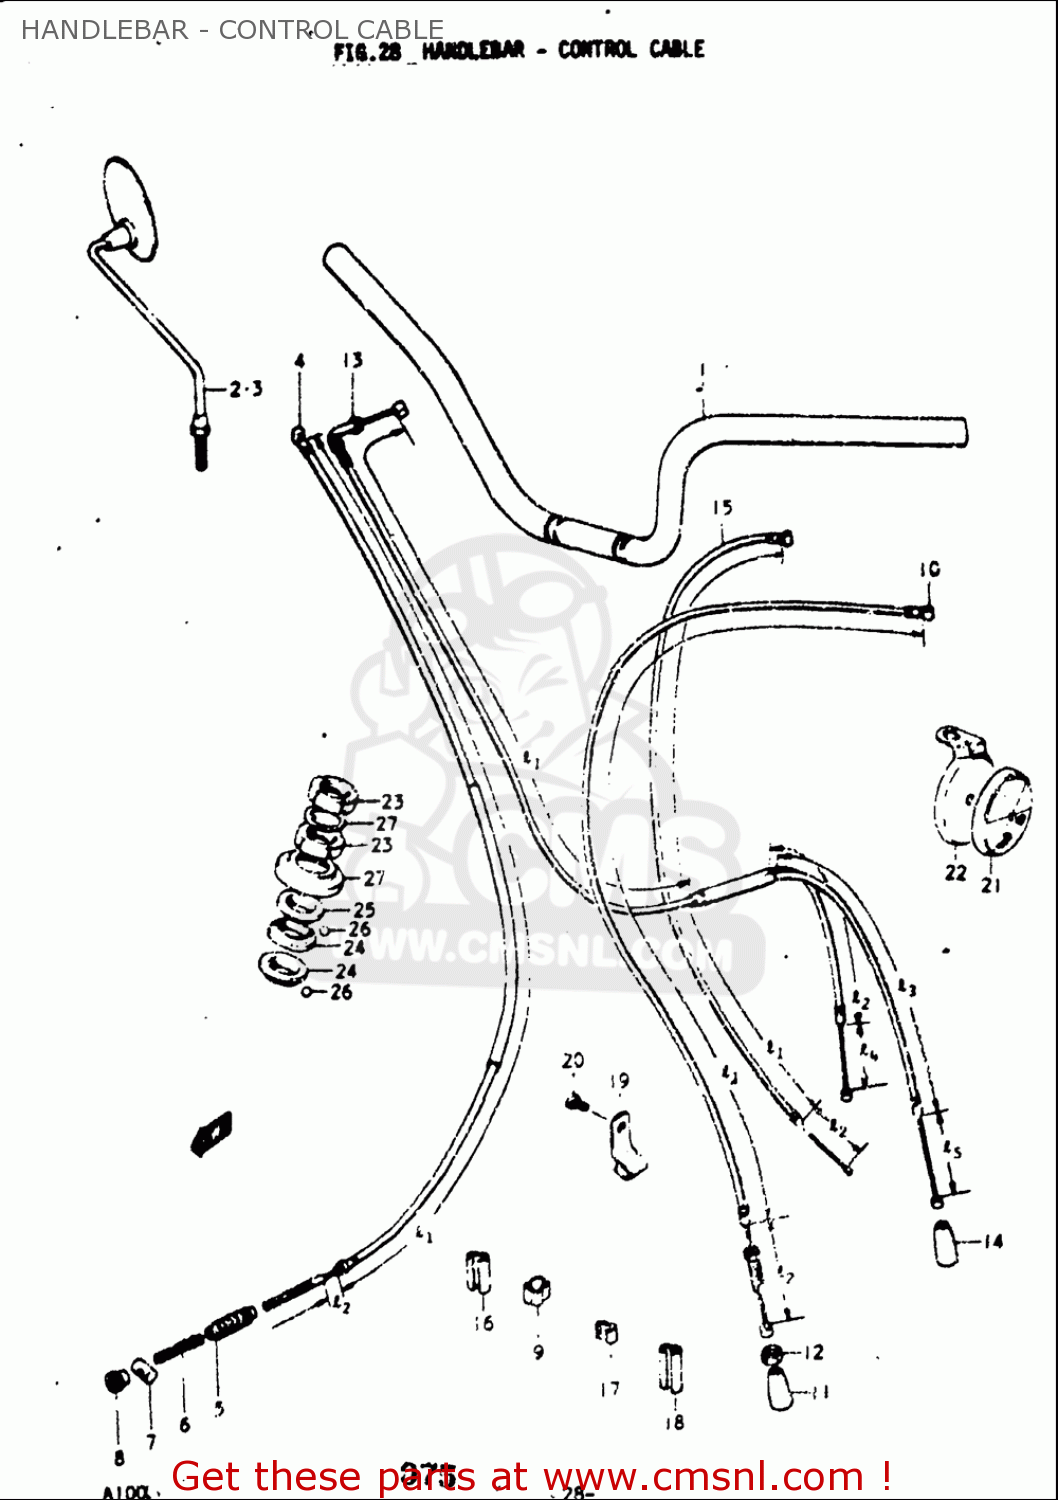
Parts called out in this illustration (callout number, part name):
2	MIRROR ASSEMBLY,RIGHT
3	MIRROR ASSEMBLY,LEFT
4	CABLE ASSEMBLY,FRONT BRAKE
5	SEAL,DUST(7X16X75)
6	SPRING
7	BRAKE ROD LEVER
8	BRAKE ROD ADJ N
10	CABLE ASSEMBLY,CLUTCH
11	SEAL,DUST(7X18X30)
12	NUT
14	SEAL,DUST(7X18X30)
15	CABLE,STARTER
16	CLIP
17	CLIP
20	BOLT
21	REFLEX REFLECTOR,RR
24	RACE,STEERING INNER UPR
25	LACE,STEERING OUTER UPR
26	BALL
